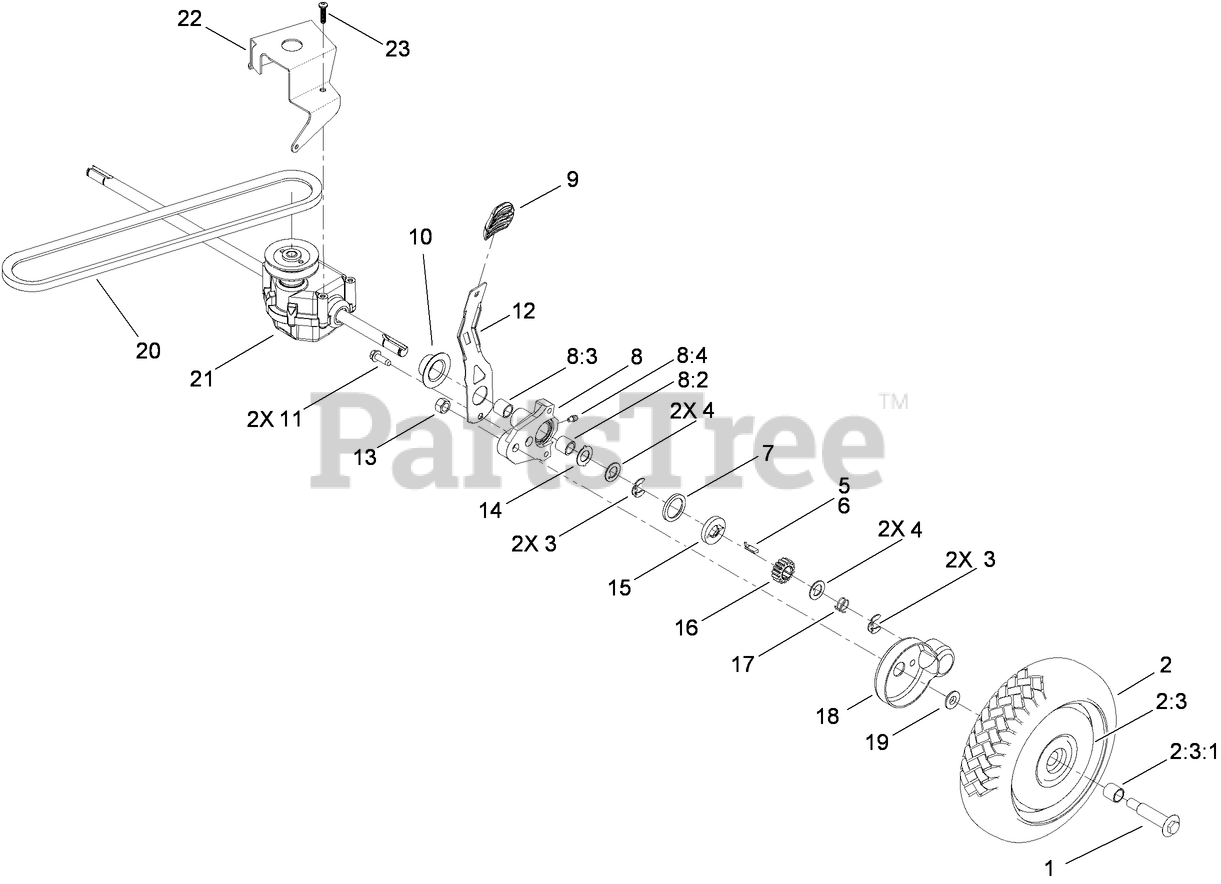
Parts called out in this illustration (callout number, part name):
1	BOLT-SHOULDER
2:3	Loose Parts Package
2:3:1	BUSHING
3	RING-RETAINING,CLIP
4	WASHER-THRUST, KEYED
5	KEY-ROCKING, RH
6	KEY-ROCKING, LH
7	RING-FRICTION
8	PIVOT ARM ASM
8:2	BUSHING
8:3	BUSHING
8:4	FITTING-GREASE
9	KNOB-LEVER, HOC
10	CAP-END
11	SCREW-HWHTF
12	ARM-SPRING
13	LOCKNUT
14	WASHER-ARM, PIVOT
15	WASHER-CLUTCH
16	GEAR-PINION
17	SPRING-COMPRESSION
18	COVER-WHEEL
19	SPACER-COVER, WHEEL
20	V-BELT
22	BRACKET-TRANSMISSION
23	SCREW-PLASTITE
